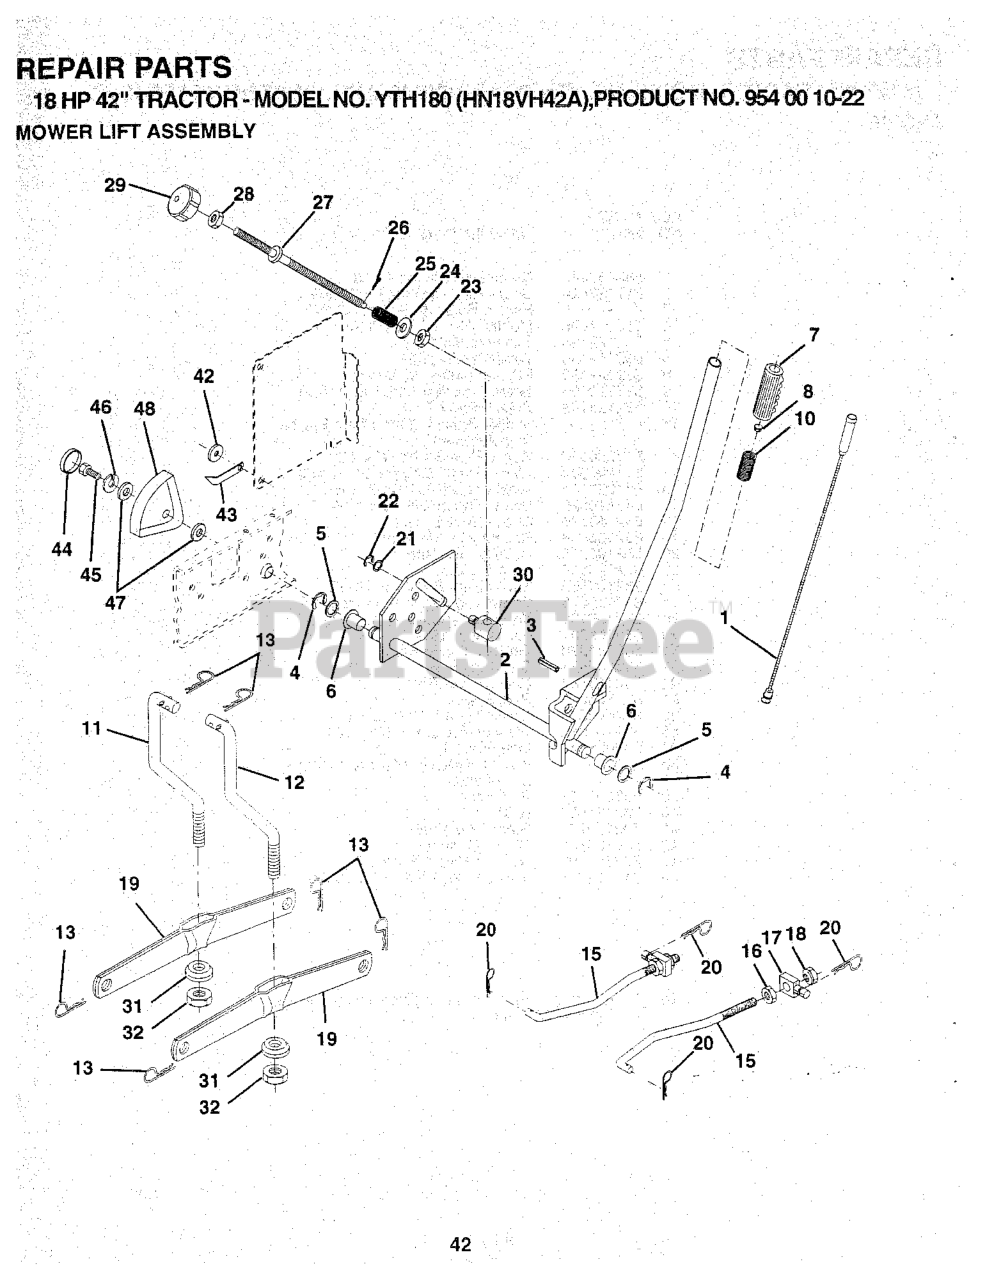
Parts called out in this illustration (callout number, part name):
1	WIRE ASM INNER
2	SHAFT ASM LIFT RH
3	PIN GROOVE
5	WASHER
6	BEARING.NYLON
7	GRIP HANDLE
8	PLUNGER BUT KIT
10	SPRING, COMP T
11	LINK LIFT LH
12	LINK LIFT RH
13	RETAINER-SPRNG RB
15	FRONT LINK
16	NUT.HEX.JAM.1/2-13
17	TRUNION
18	NUT.LK.W/WSH.1/2.
19	ARM.REAR.SUSPENSION
20	SPRING RETAINER
21	Washer 15/32 x 3/4 x 16 Gauge
22	Ring, Klip #T5304-37
25	SPRING**
26	COTTER PIN
27	ROD LIFT LT
28	NUT
29	KNOB INF 3/8-16
30	TRUNION LT
31	BEARING PIVOT
43	POINTER HGT
45	BOLT.FIN.HEX.5/16-18UNC X 1.00
46	WASHER.LOCK.HVY.HLCL.SPR.5/16
48	HEIGHT INDICATOR
